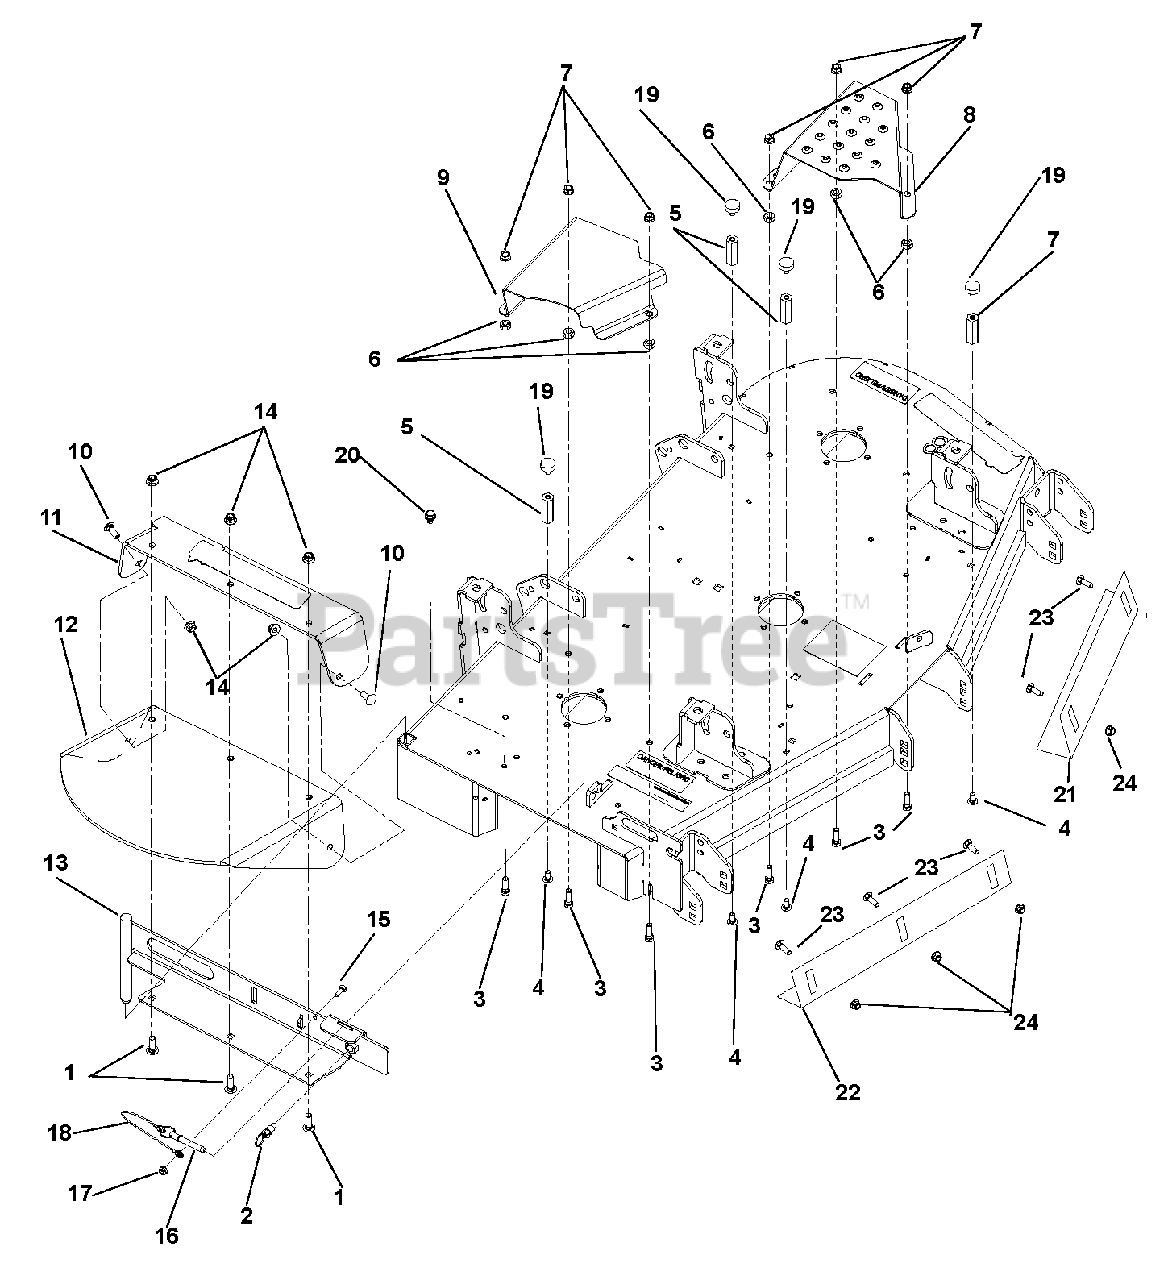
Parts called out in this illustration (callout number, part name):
1	Bolt, Round Head Square Neck .38-16 x 1.25
2	Pull Pin
3	Bolt, Hex .38-16 x 1.25
4	Bolt, Round Head Square Neck .31-18 x .75
5	Nut, Coupling .31-18 x 3.00
6	Nut, Heavy Hex .38-16
7	Nut, Flange .375-16
8	Guard, Left Hand Deck Belt, 44 – 52 (991079, 080, 095, 096, 102, 103)
9	Guard, Right Hand Deck Belt, 48 – 52 (991079, 080, 095, 096, 102, 103)
10	Bolt, Round Head Square Neck .38-16 x 1.00
11	Rubber Discharge Chute Support
12	Chute, Rubber Discharge
13	Weldment, Discharge Chute Support, 48" (991079, 095, 102)
14	Nut, .38-16 Nyloc Flange
15	Bolt, Hex .25-20 x .75 (991079, 095, 102)
16	Pin, Spring Ball .375OD x 1.50 (991079, 095, 102)
17	Nut, Locking Top Flange .25-20 (991079, 095, 102)
18	Cable, 6.0 Lanyard, Nylon (991079, 095, 102)
19	Bumper, Rubber
20	Screw, Self Tapping .38-16 x .50
21	Baffle, 48" Left Hand Vacuum (991079, 095, 102)
22	Baffle, 48" Right Hand Vacuum (991079, 095, 102)
23	Bolt, Round Head Square Neck .31-18 x .75 Grade 5
24	Nut, Lock Nyloc .312-18
